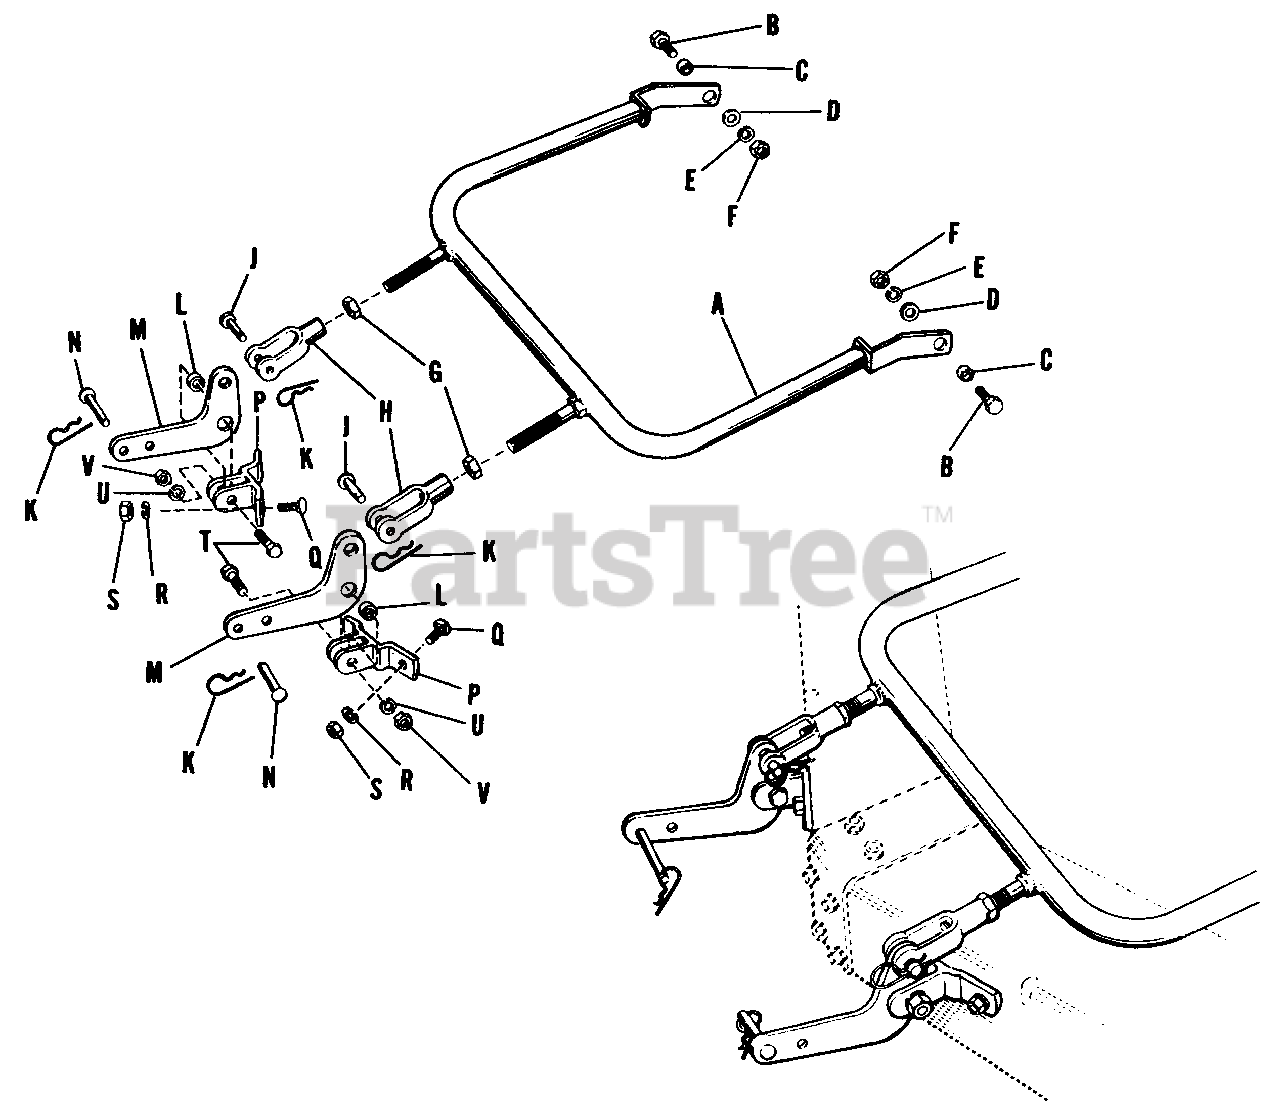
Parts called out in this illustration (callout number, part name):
A	Bail Assembly
B	Capscrew, Hex Hd., 1/2"-13 NC x 1-1/4" lg.
D	Washer, Plain, 1/2"
E	Washer, Lock, 1/2"
F	Nut, Hex, Full, 1/2"-13 NC
G	Nut, Hex, Jam, 1/2"-20 NF
H	Yoke End, Adjusting
K	Clip, Spring
M	Rocker Arm
N	Pin
P	Bracket Assembly, Front
Q	Bolt, Carriage,3/8"-16 NC x 1"
R	Washer, Lock, 3/8"
S	Nut Hex, Full, 3/8"-16 NC
T	Capscrew, Hex, 1/2"-13 NC x 1-1/4"
U	Washer, Lock, 1/2"
V	Nut, Hex, Full, 1/2"-13 NC
